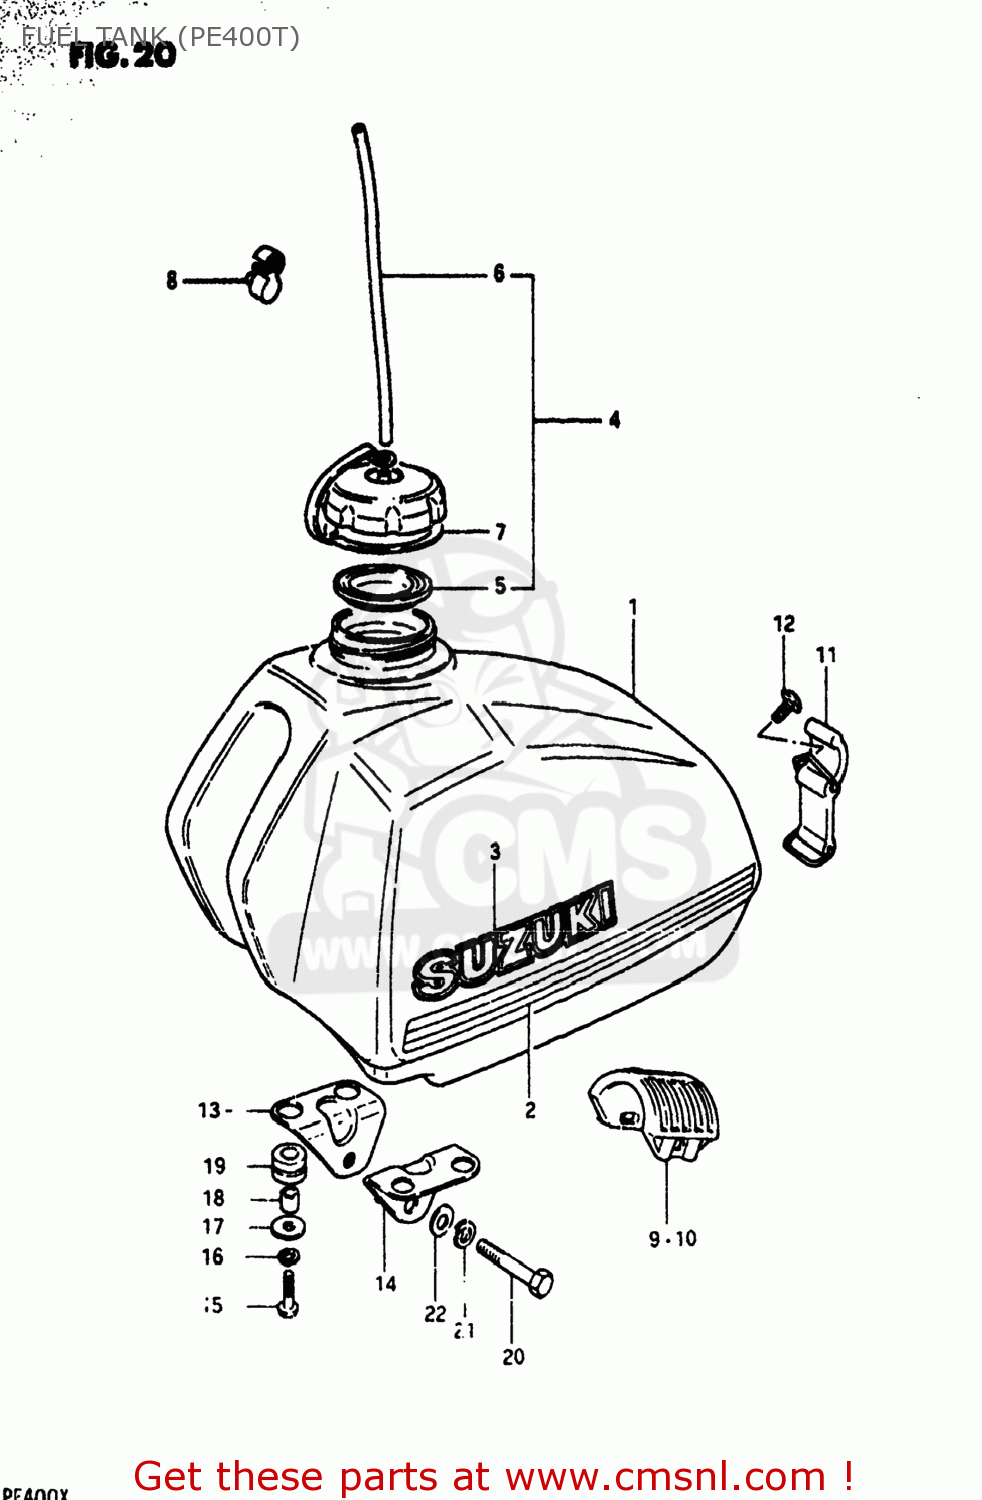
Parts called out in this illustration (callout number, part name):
1	TANK ASSEMBLY,FUEL
2	TAPE SET,FUEL TANK
3	EMBLEM
4	CAP,FUEL TANK
5	GASKET,FUEL TANK CAP (NAS)
6	HOSE
7	BAND,FUEL TANK CAP
8	CLAMP,BREATHER HOSE
9	CUSHION,FUEL TANK
10	CUSHION,FUEL TANK
11	BAND
12	SCREW(6X18)
13	BRACKET,FUEL TANK
14	BRACKET,FUEL TANK,LOWER
15	SCREW
16	LOCK WASHER
17	WASHER (6.5X24X1.6)
18	SPACER(6.8X12X11)
19	CUSHION
20	BOLT
21	LOCK WASHER
22	WASHER
